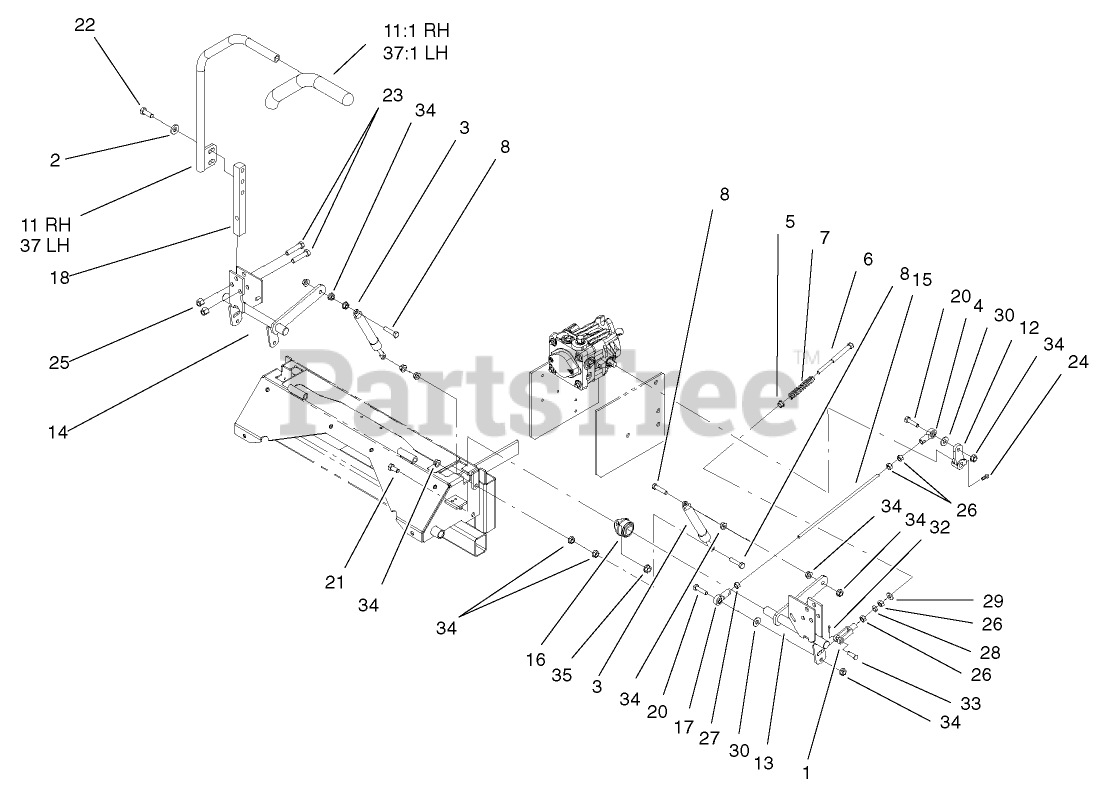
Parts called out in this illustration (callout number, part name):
1	YOKE-ADJUSTABLE
2	WASHER-BELLEVILLE
3	DAMPER-CONTROL
4	BALLJOINT-RH
5	BUSHING-FLANGED
6	BOLT-RETURN, NEUTRAL
7	SPRING-RETURN, NEUTRAL
8	SCREW-HH
11	RH LEVER ASM
11:1	GRIP-CONTROL, MOTION
12	ARM-CONTROL, PUMP
13	CONTROL-MOTION, LH
14	CONTROL-MOTION, RH
15	LINKAGE-PUMP/LEVER
16	BEARING-FLANGE, SIDE
17	BALLJOINT-LH
18	ARM-SHAFT, CONTROL
20	SCREW-HH
21	SCREW-HH
22	SCREW-HH
23	SCREW-HH
24	SCREW-SET
25	NUT-LOCK, NI
26	NUT-HEX
28	NUT-JAM
29	WASHER-FLAT
30	WASHER-FLAT
32	PIN-COTTER
33	PIN-CLEVIS
34	NUT-HF
35	NUT-HHF, WHIZ
37	LH LEVER ASM
37:1	GRIP-CONTROL, MOTION
